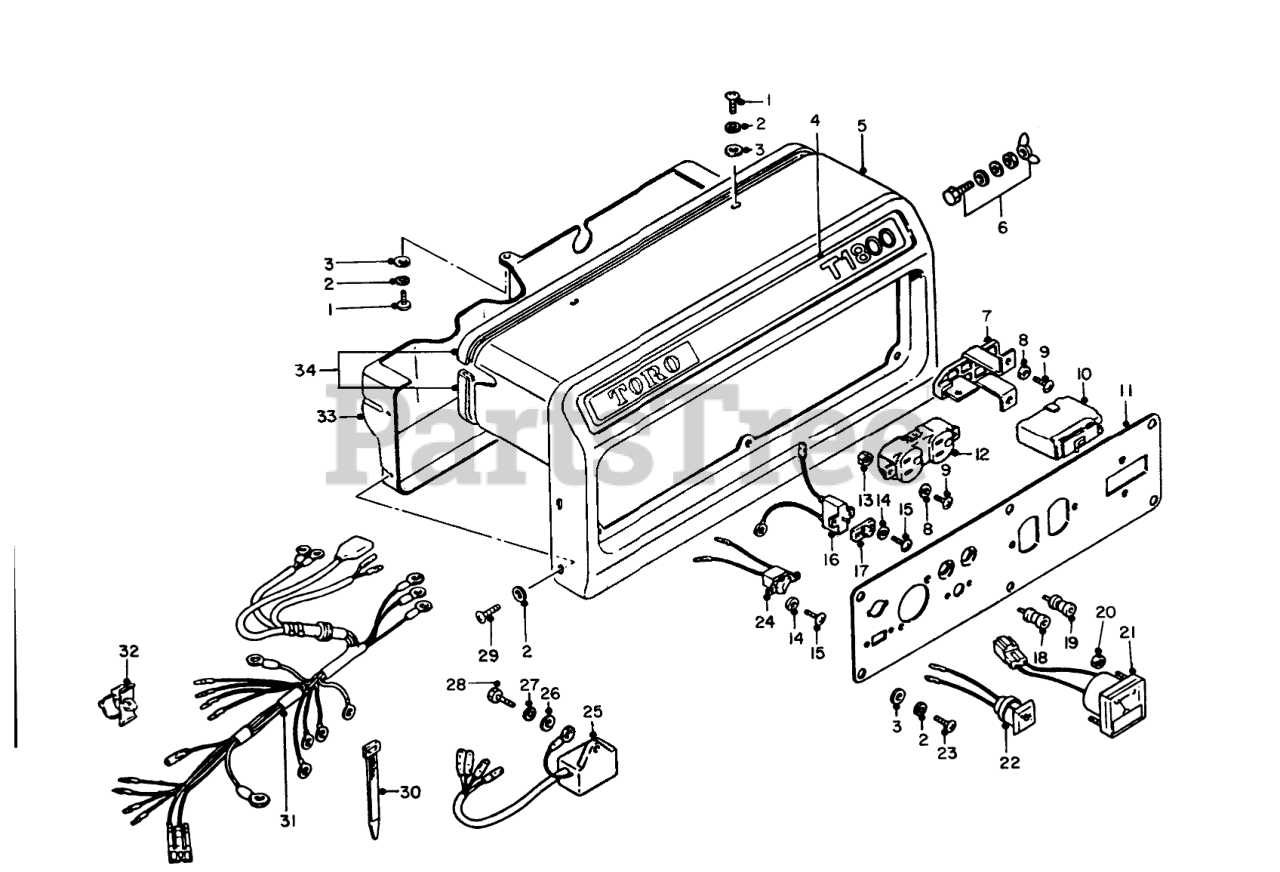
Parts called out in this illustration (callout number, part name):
1	SCREW
2	Washer
3	WASHER
4	Emblem-Toro T1800
5	Panel-Control
6	GROUND TERMINAL
7	BREAKER HOLDER
8	Washer
9	Screw
10	Circuit Breaker
11	PLATE
12	RECEPTACLE
14	Washer
15	Screw
16	Protector-Circuit
18	TERMINAL-
21	Meter-Voltage
23	Screw
24	Switch
25	OIL LEVEL UNIT
26	Washer
27	LOCKWASHER
29	Screw
30	Clamp
31	CONTROL HARNESS
32	Clamp
33	Panel-Rear
